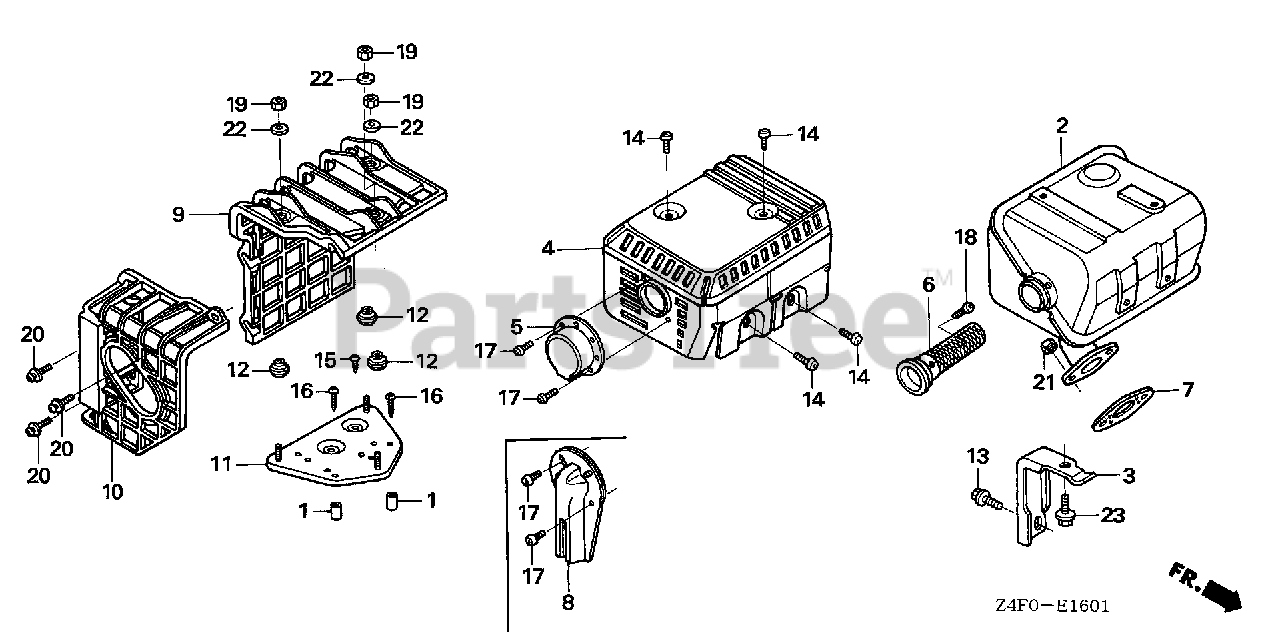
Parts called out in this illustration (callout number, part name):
1	COLLAR, AIR CLEANER HOUSING
2	MUFFLER (SILENT)
2	MUFFLER (ARRESTER)
3	STAY, MUFFLER
4	PROTECTOR, MUFFLER (SILENT)
5	CAP, MUFFLER
6	ARRESTER, SPARK
6	ARRESTER, SPARK (SILENT)
7	GASKET, MUFFLER
8	DEFLECTOR, MUFFLER
9	COVER, MUFFLER
10	COVER, RR. MUFFLER
11	BASE, MUFFLER COVER
12	SPACER, MUFFLER COVER
13	BOLT, FLANGE (6X13) (CT200)
14	SCREW, TAPPING (5X8)
15	SCREW, TAPPING (5X8)
16	SCREW, TAPPING (5X25)
17	SCREW, TAPPING (4X6)
18	SCREW, TAPPING (4X6)
19	NUT, HEX. (5MM)
20	SCREW-WASHER (6X20)
21	NUT, HEX. (8MM)
22	WASHER, PLAIN (5MM)
23	BOLT, FLANGE (6X12)
